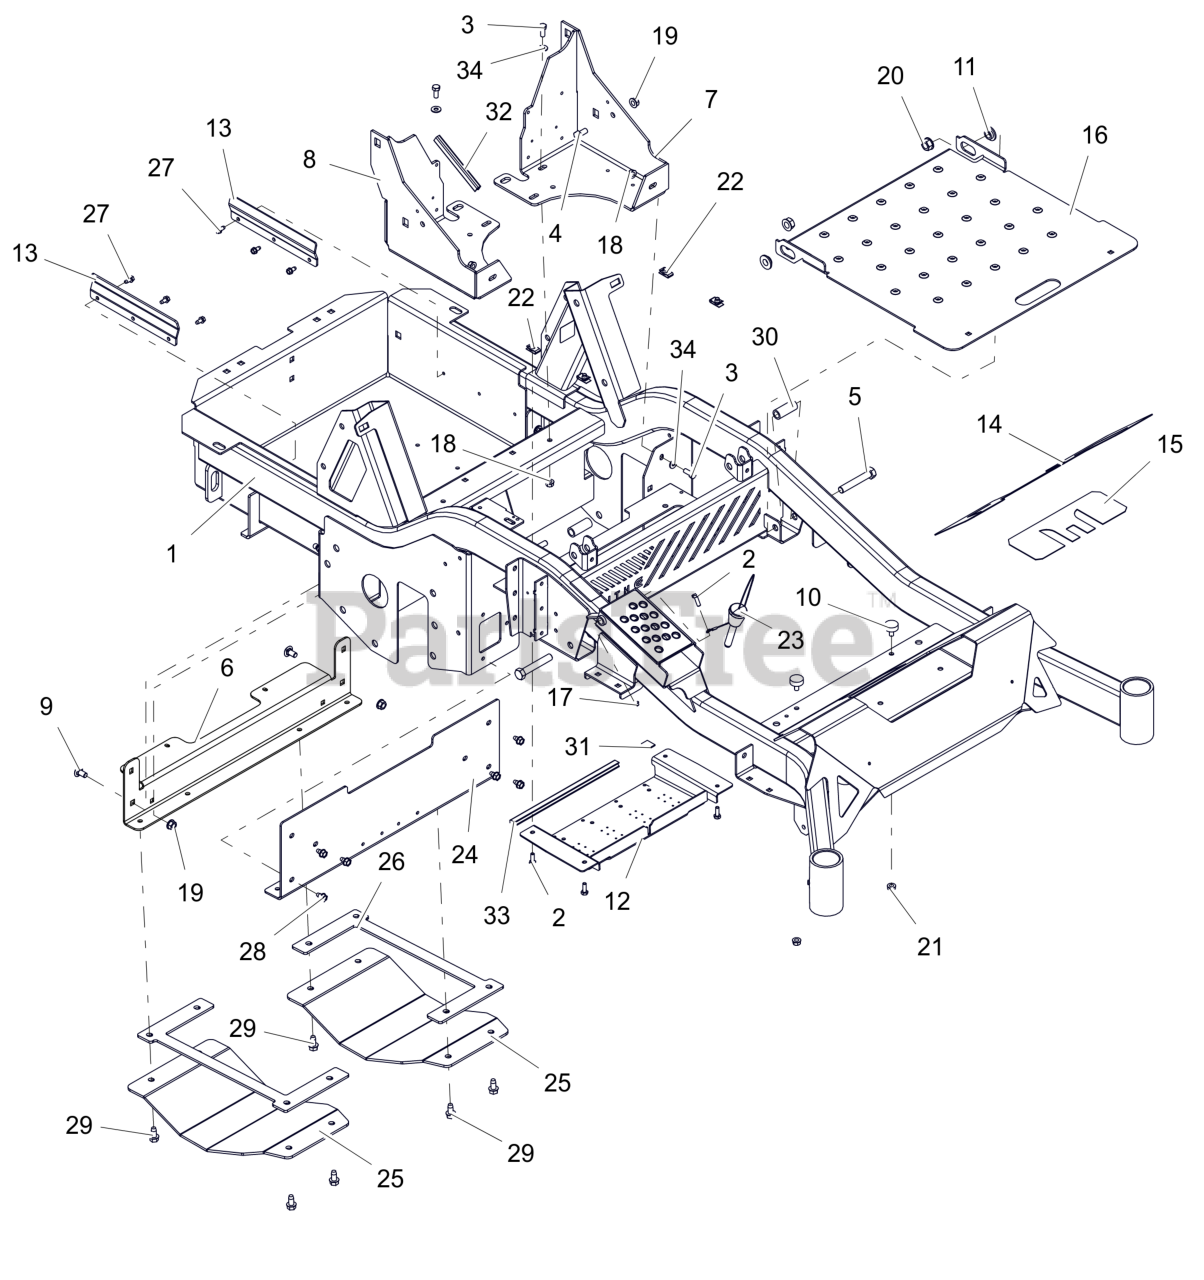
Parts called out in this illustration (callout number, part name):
1	KIT,EV FRAME(SM)W/DECALS-A
2	BLT, HEX .25-20X.75 G5 ZCC
3	BLT,HEX .31-18X.75 G5 ZCC
4	BLT,HEX .38-16X.75 G5 ZCC
5	BLT, HEX .50-13X3.00 G5 ZCC
6	BRKT, SKID PLATE MTG. (ORANGE)
7	BRKT, SUPPORT ROPS -LH (ORANGE)
8	BRKT, SUPPORT ROPS-RH (ORANGE)
9	BLT, RHSSN .38-16X.75 G5 ZCC
10	BUMPER, RUBBER
11	BSHG-FLG .515X.750X.395X1.120
12	COVER, BOTTOM ACCESS -OPEN (ORANGE)
13	DEFLECTOR, BATTERY -EV (ORANGE)
14	GRIP, FRONT
15	GRIP, TAPE FRONT
16	PANEL, ACCESS
17	NUT-LK-CTR-FLG .25-20 ZC120
18	NUT,LK-CTR-FLG .31-18 GF ZCC
19	NUT-LK-CTR-FLG .375-16 GF ZCC
20	NUT-LK-CTR-FLG .500-13 GG ZCC
21	NUT,SPNLK-FLG .31-18 G5 ZCC
22	NUT-RTNR .25-20X.56
23	PIN, MAGNETIC .50X2.50
24	PLATE, FRONT FRAME (ORANGE)
25	PLATE, SKID (BLACK)
26	PLATE, SKID TENSION (BLACK)
27	SCR-TAP .25-20X.50 HWH ZCC
28	SCR,TAP .312-18X.50 HWH TR ZCC
29	SCR,TAP .375-16X.75 HWH TR ZCC
30	SPACER, .515X.75X1.83
32	STRIP, COWL
33	STRIP, COWL
34	WSHR, FLT .312X.734X.065 ZCC
